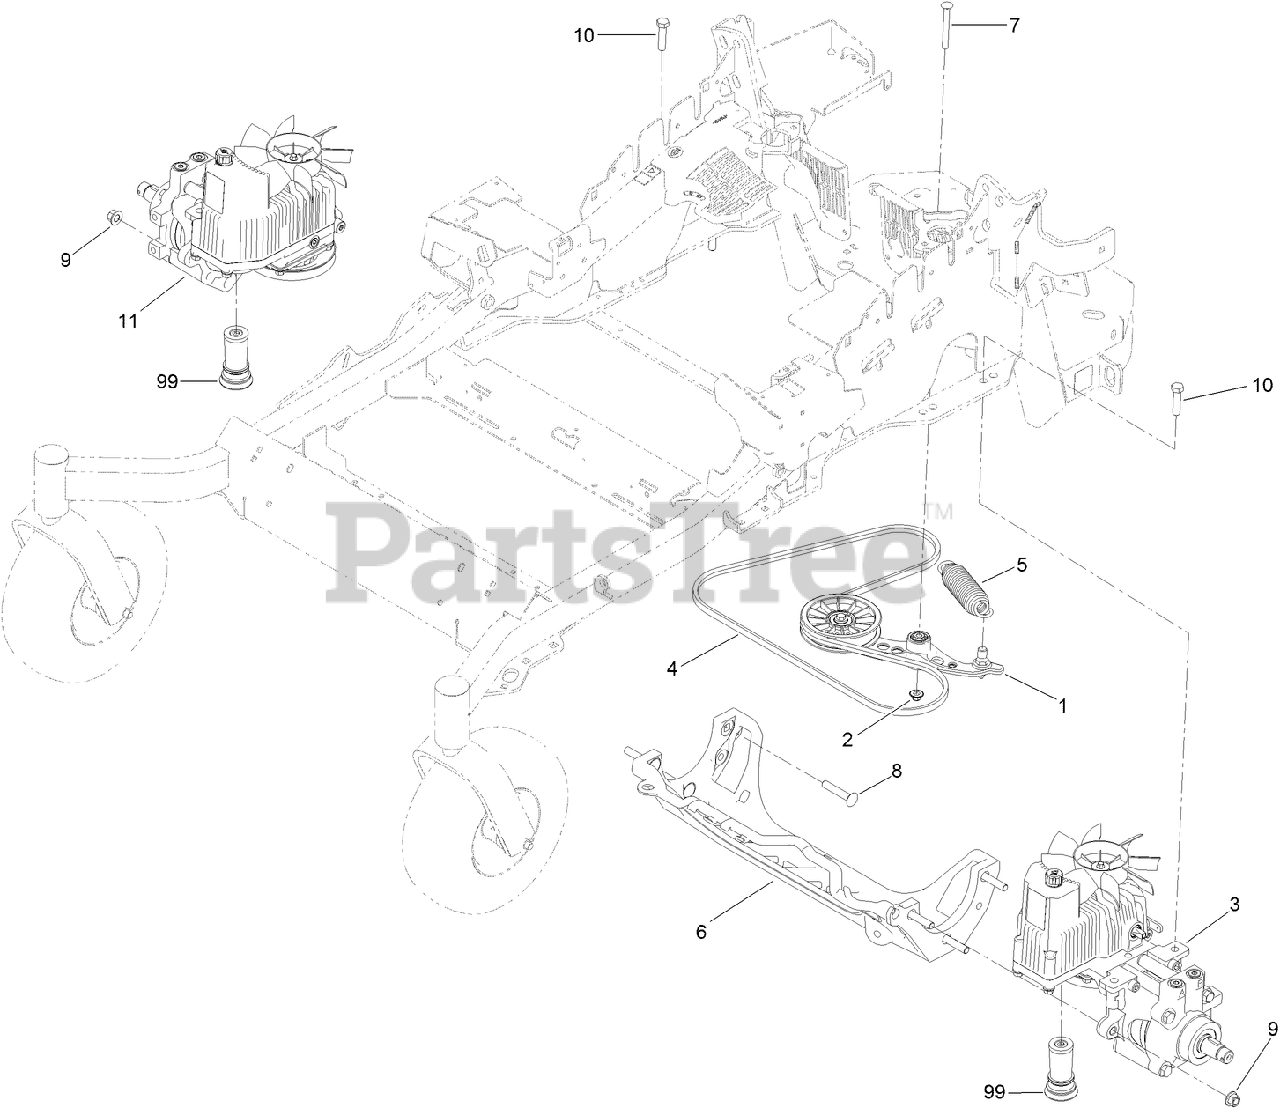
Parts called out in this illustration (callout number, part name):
1	PUMP IDLER ASM
2	NUT-FLANGE, NI
3	LH HYDRO ASM (16CC W/ SHOCK)
4	BELT
5	SPRING-EXTENSION
6	CRADLE-HYDRO
7	BOLT-SHOULDER, CARRIAGE
8	SCREW-CARR
9	NUT-LOCK
10	SCREW-HH
11	RH HYDRO ASM (16CC W/ SHOCK)
99	FILTER-HYDRO
